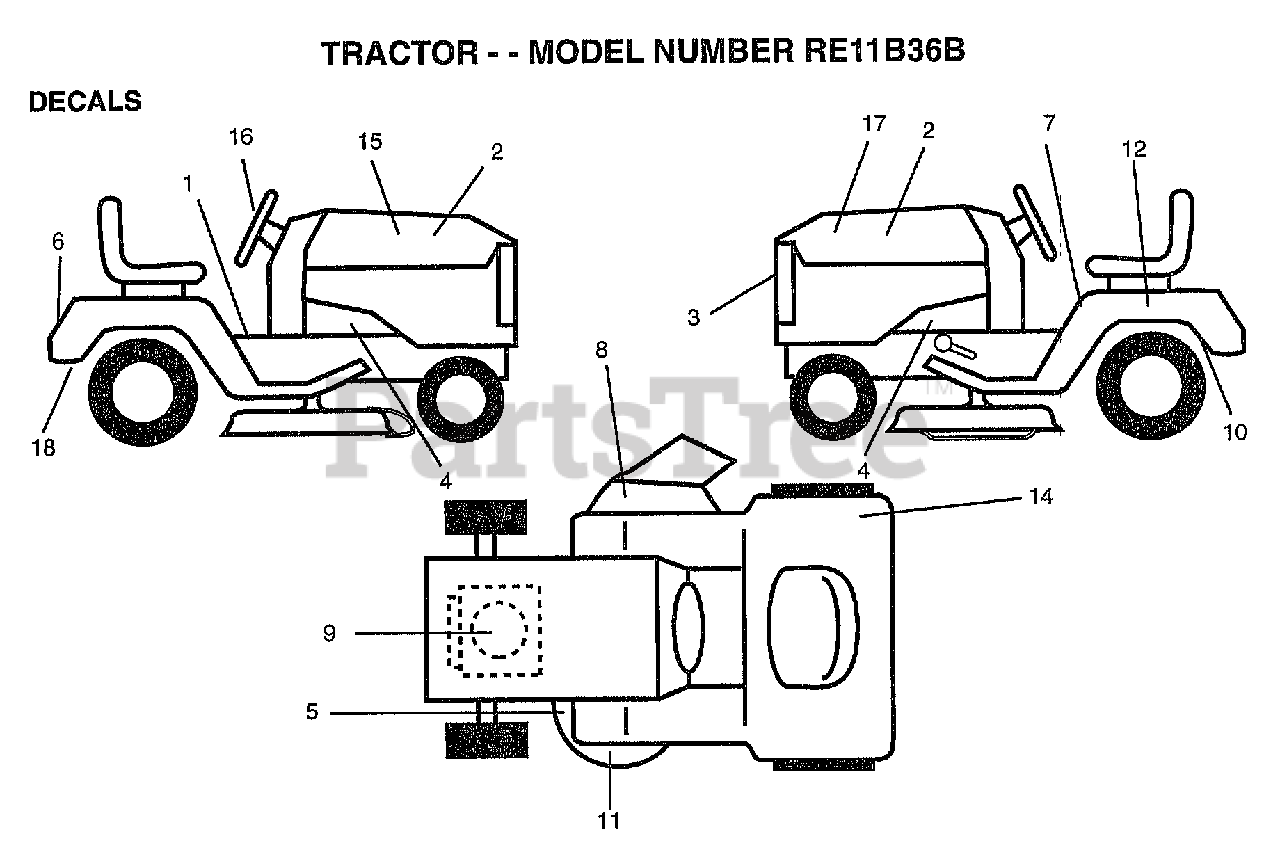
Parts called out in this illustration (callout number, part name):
1	DECAL CLUTCH/BRAK
2	DECAL.HOOD.INSERT
3	GRILL DECAL
4	"DECAL CHASSIS,HOT"
5	DECAL.V.BELT
6	FENDER DECAL
7	DECAL.READ.O.MANU
8	DECAL.DANGER.CUTF
10	DECAL.DRAWBAR.LDL
12	DECAL.BATRY.3-3908
15	DECAL HD RLY RH
16	"DECAL,STR WHL"
17	DECAL HD RLY LH
18	DECAL.EURO.ST.CE.
